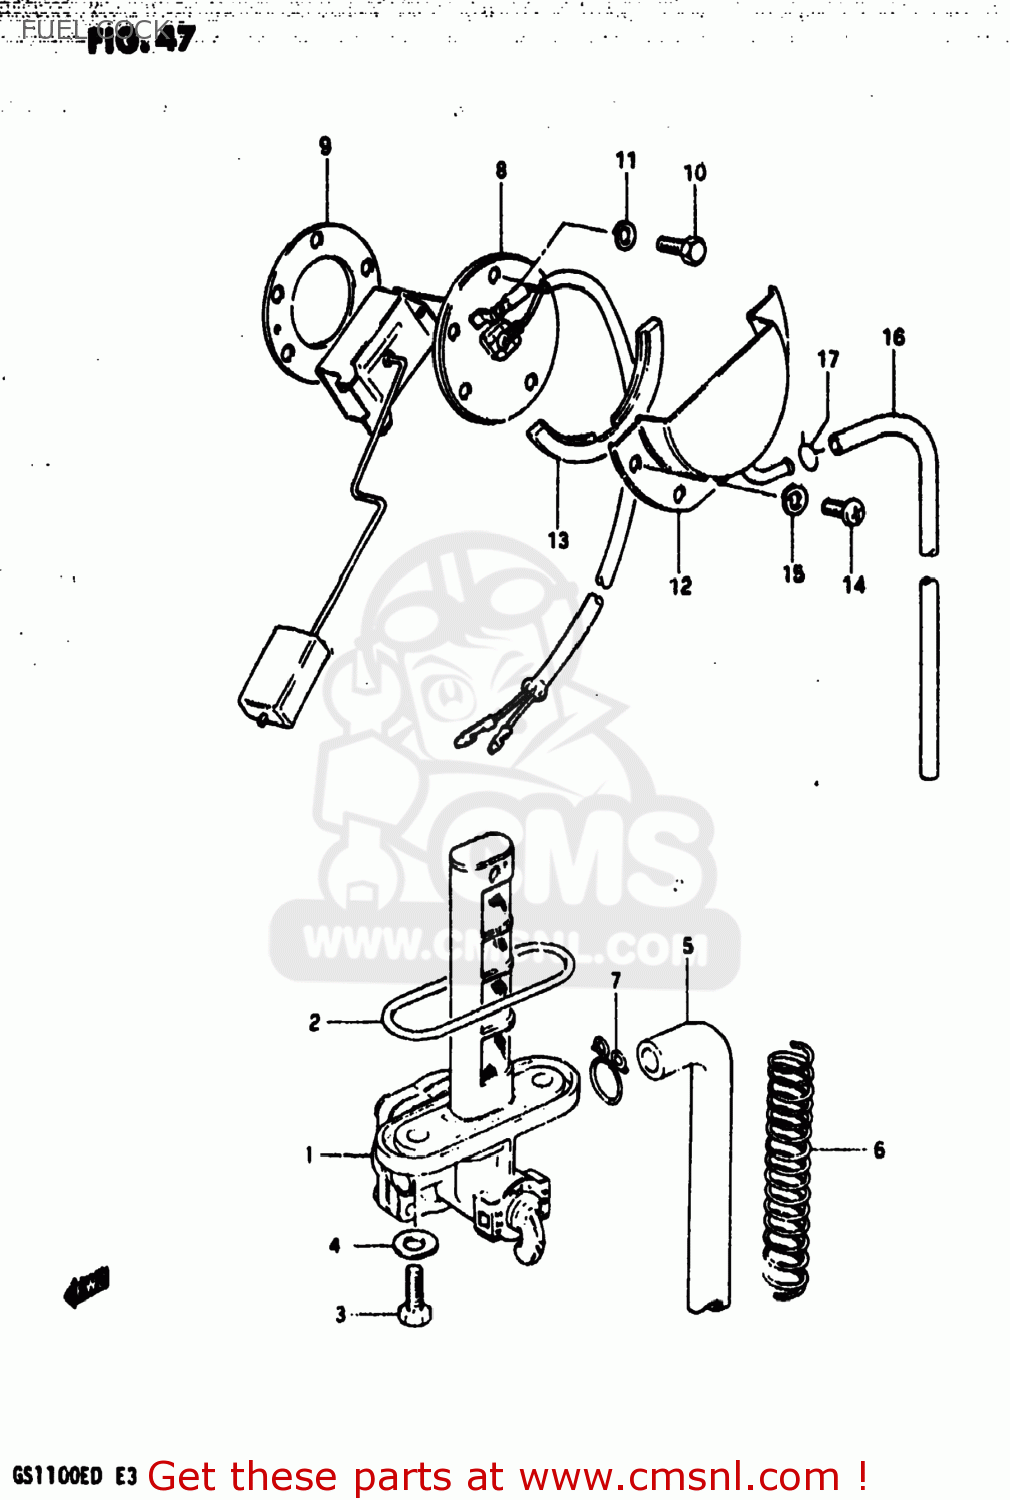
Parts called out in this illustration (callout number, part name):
1	COCK ASSEMBLY,FUEL
2	O RING
3	BOLT(6X20)
4	GASKET
5	HOSE
6	SPRING
7	CLIP
8	GAUGE ASSEMBLY,FUEL LEVEL
9	GASKET,FUEL LEVEL GAUGE (NAS)
10	BOLT
11	LOCK WASHER
12	PLATE,FUEL DRAIN
13	GASKET (NAS)
14	SCREW
15	LOCK WASHER
16	HOSE,FUEL
17	CLIP
